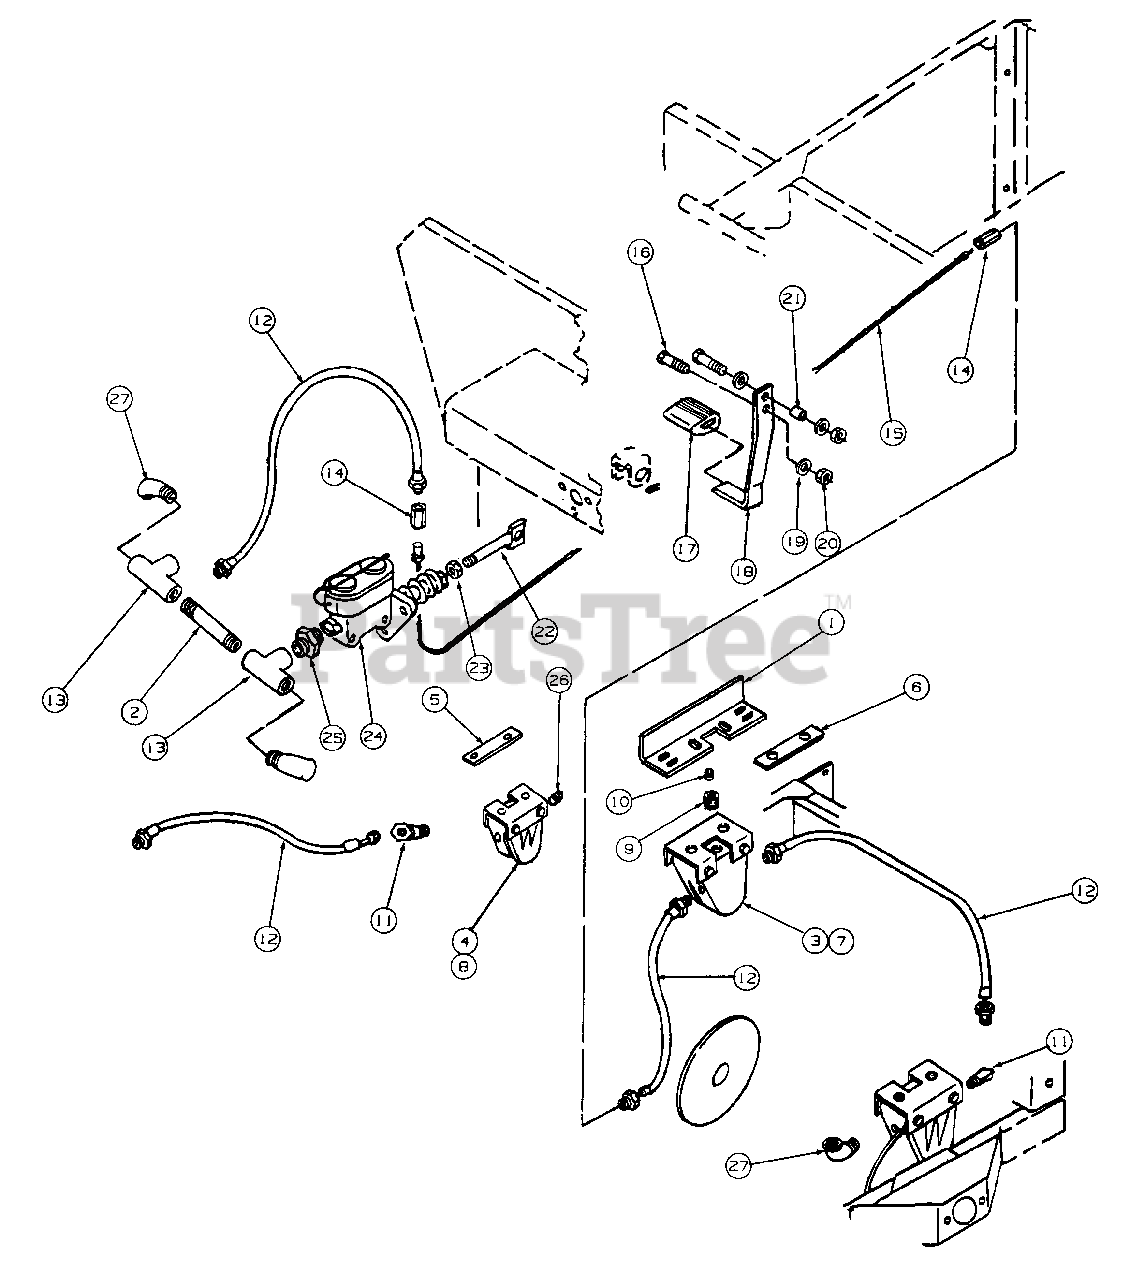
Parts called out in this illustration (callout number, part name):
1	Bracket, Rear Brake Mtg
2	Nipple, Pipe, 1/8 X 3.0
3	Caliper, Rear Brake, H20
4	Caliper, Front Brake, H10
5	Nut, Front Strap
6	Nut, Rear Strap
7	Pad Kit, Rear Brake, H20
8	Pad Kit, Front Brake, H10
9	Adapter, Bleeder
10	Fitting, Bleeder
11	Fitting, Brass, 45 Degree
12	Hose, Hydraulic Brake, 1/8 X 19-1/2
13	Tee, Pipe, 1/8
14	Coupler, Double Female, 3/16
15	Brake Line, Steel, 3/16 X 51
16	Screw, Hex Hd Mach, 3/8-16 X 1.75
17	Pad, Brake Pedal
18	Lever, Brake Pedal
19	Washer, Flat,
20	Nut, Center Lock, 3/8-16
21	Spacer, 3/8 X 1/2
22	Bolt, Spade
23	Nut, Jam, .44-20
24	Master Cylinder, Hydraulic
25	Adaptor, 1/2-20 X 1/8 NPT
26	Plug, Pipe, 1/8
27	Elbow, Street, 45 Degree, 1/8
